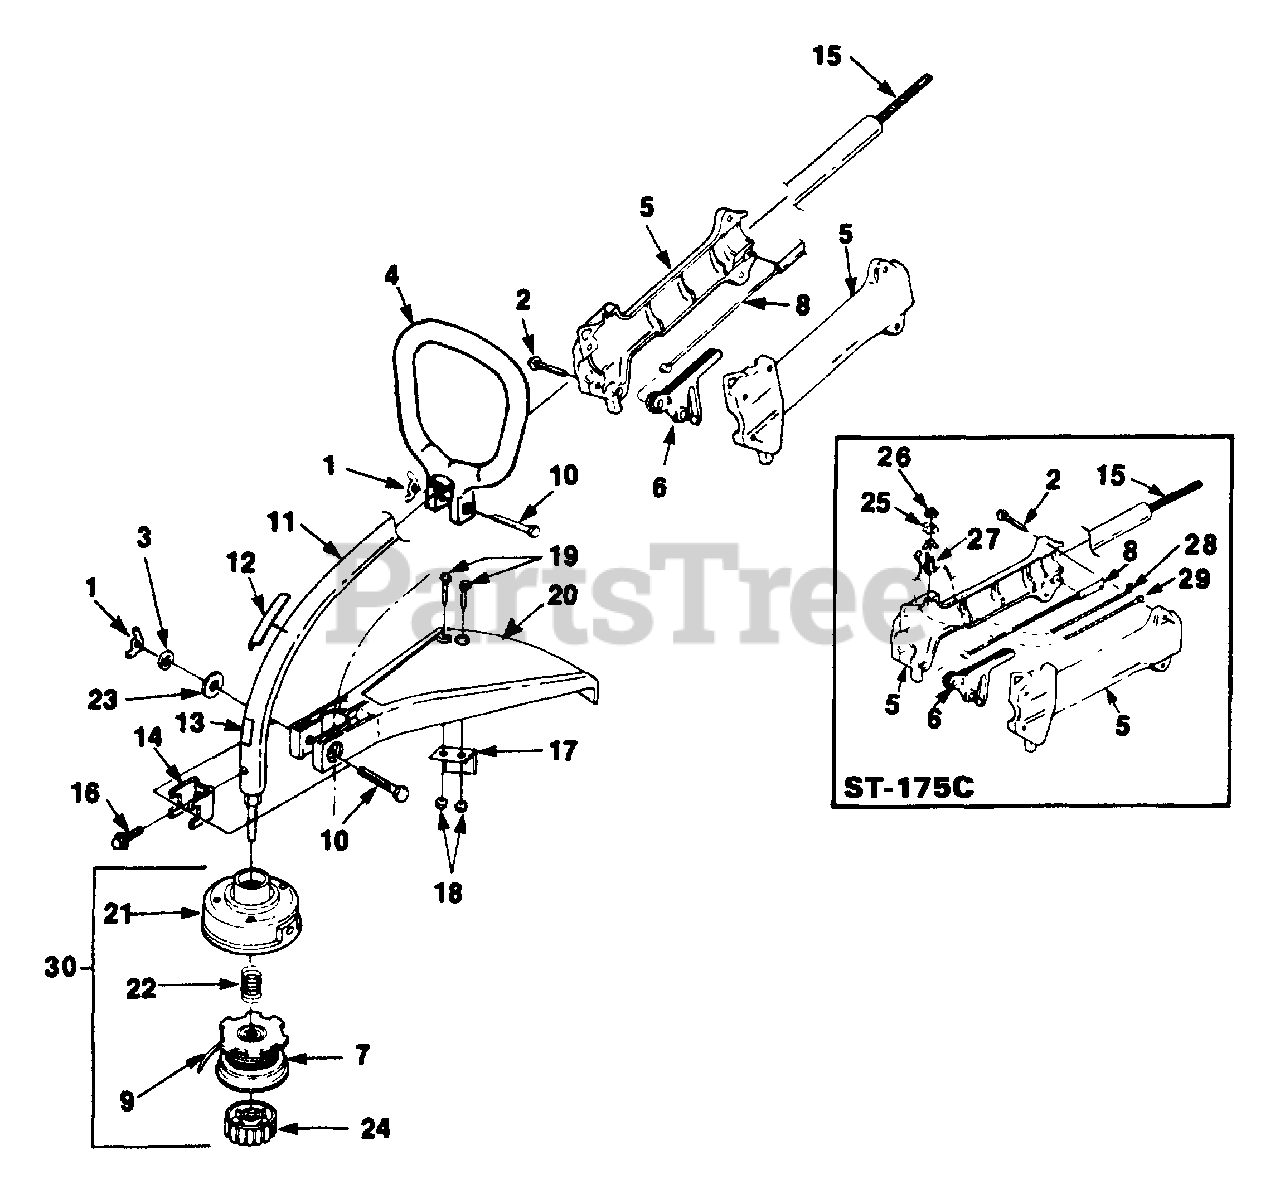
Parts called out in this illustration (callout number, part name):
1	NUT-Wing
2	SCREW-Thread Form (#8 X 3/4")
3	WASHER-Lock (1/4")
4	HANDLE-Front
5	HANDLE GRIP ASSEMBLY
6	TRIGGER
7	SPOOL & STRING (Dual Line) (.080 Dia)
8	CABLE-Throttle
9	LINE-Replacement (.080 Dia) (100 Ft.)
10	SCREW-Cap Hex Hd (1/4-20 x 2")
11	HOUSING-Driveshaft
12	DECAL-Starting Inst
13	DECAL-Warning
14	CLAMP
15	SHAFT-Flexible
16	SCREW-Thread Form (#10 x 1/2")
17	BLADE-Cut-Off
18	NUT-Hex (10-24)
19	SCREW-Mach Hex Hd (10-24 X 1")
19	SCREW-Mach Hex Hd (10-24 x 1")
20	DEFLECTOR-Grass
21	HOUSING & EYELET-Dual Line
22	SPRING-Compression
23	WASHER-Flat (1/4")
24	RETAINER-Spool
25	PLATE-Indicating
26	NUT-Toggle Switch
27	TOGGLE SWITCH
28	LEAD-Electrical
29	LEAD-Ground
30	STRINGHEAD COMP (.080 Dia Line)
